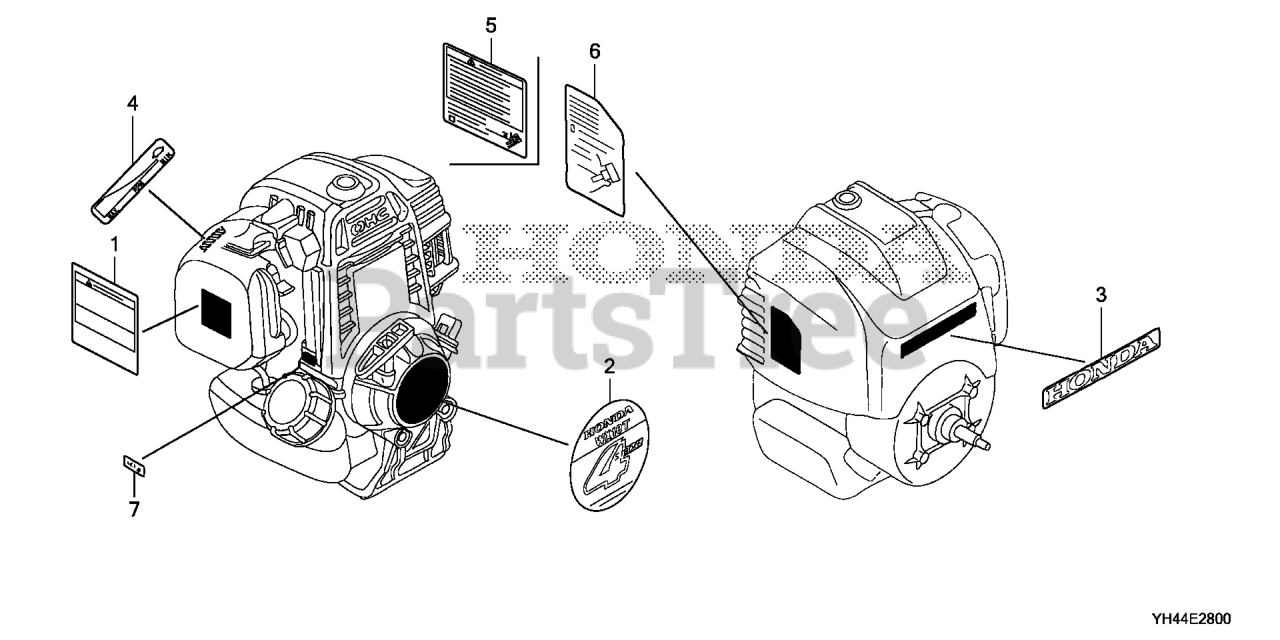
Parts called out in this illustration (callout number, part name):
1	MARK, OPER CAUTION
4	MARK, THROTTLE INDICATION
5	LABEL, SPARK WARNING
7	MARK, TYPE (AD8)
